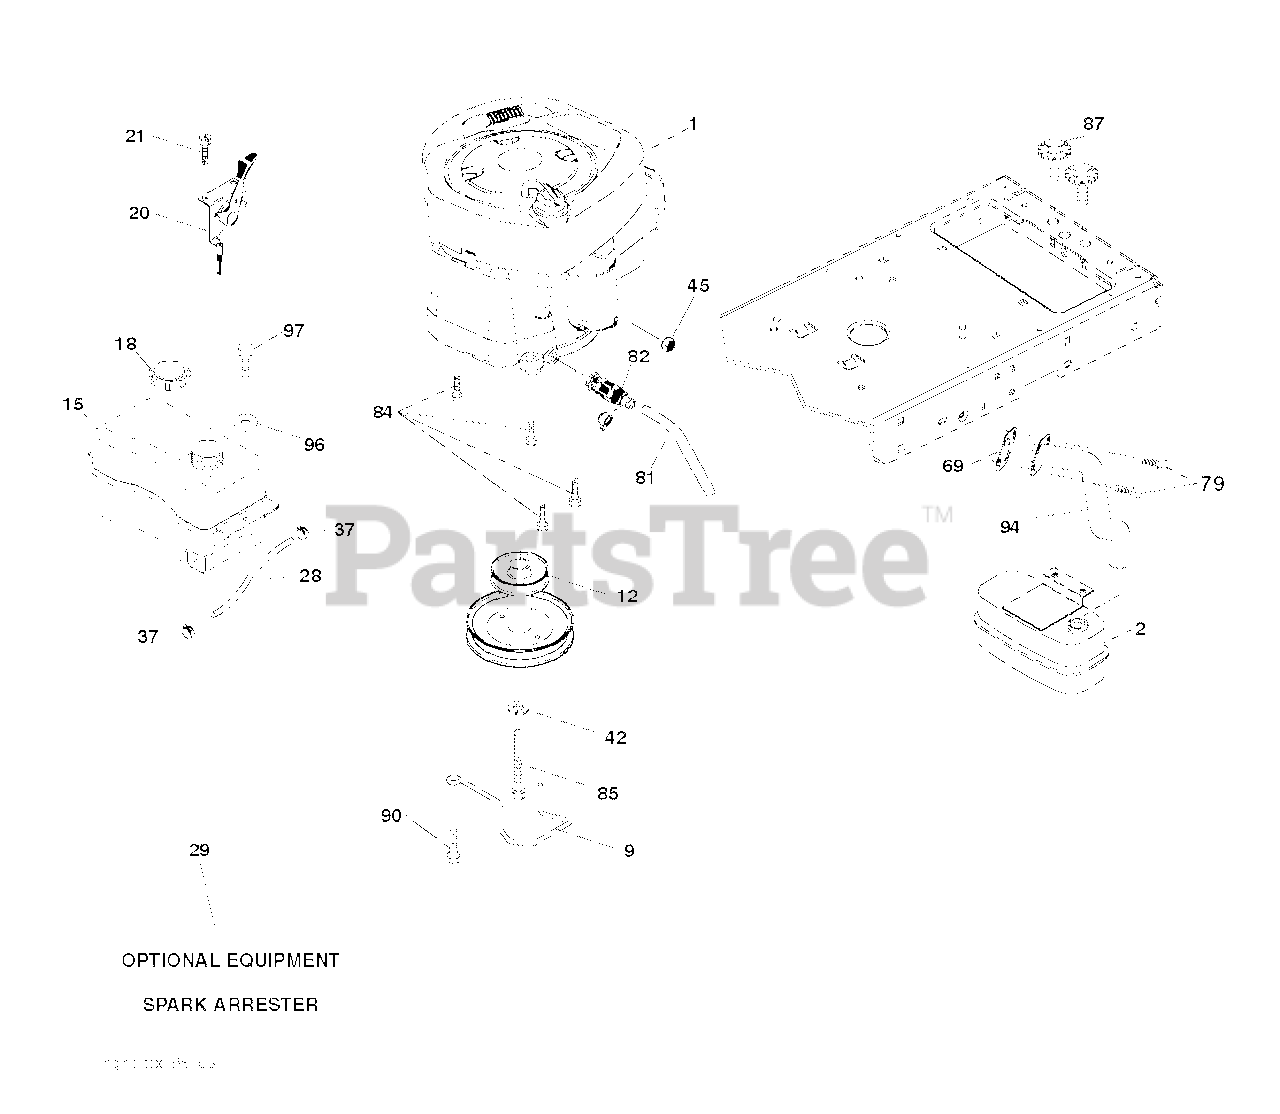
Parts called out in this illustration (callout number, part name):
2	MUFFLER.SINGLE.CYL.KOHL/B&S
9	KEEPER.BELT.ENGINE.3.25
12	PULLEY ENGINE
15	RP TANK FUEL FRT 1.5 GAL
18	CAP ASM.FUEL.2.25"FR.
21	SCREW.#10 X 0.750.BOS (2 2)
28	LINE.FUEL.20"FRONT.EMI
29	SPARK ARRESTOR KIT
37	HOSE CLAMP
42	LOCKWASHER
45	NUT
79	SCREW.SOCKET HD.5/16-1
81	TUBE, DRAIN OIL ASM.
82	VALUE.OIL.DRAIN
84	SCREW.3/8-16
85	BOLT HEX 7/16-20X4-1/4"
87	BOLT, 5/16-18 X 1 3/4
90	SCREW 3/8-16X1
94	EXHAUST.TUBE.B&S.
97	SCREW HEXWSHR 1/4-20X3/4
